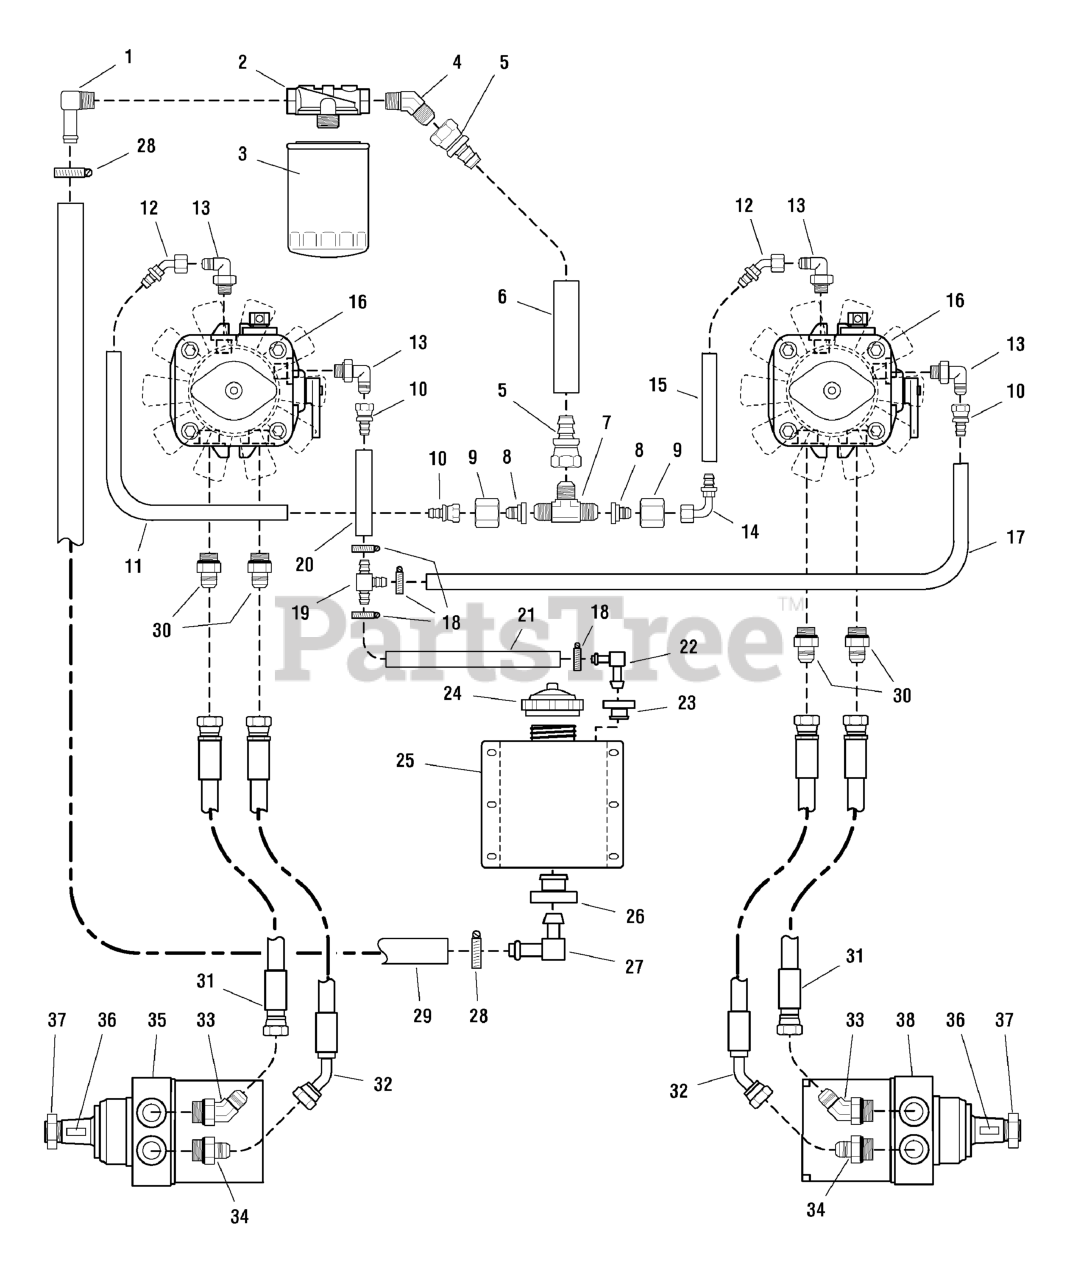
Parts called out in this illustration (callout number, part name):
1	FITTING, 1/2" NPT, 90 Deg.
2	FILTER HEAD
3	FILTER, HYDRAULIC, SERVICE PART (PKG)
4	FITTING, 1/2" NPT, 45 Deg.
5	FITTING, Straight Swivel
6	HOSE, Hydraulic, 7-1/2"
7	FITTING, Tee
8	ADAPTER, Tee
9	NUT, Adapter
10	FITTING, Straight Swivel
11	HOSE, Hydraulic, 13-3/4"
12	FITTING, 45 Deg. Swivel
13	FITTING, O-Ring, 90 Deg.
14	FITTING, 90 Deg. Swivel
15	HOSE, Hydraulic, 6-3/4"
16	HYDRAULIC PUMP, 10CC, w/ FAN
16	HUB & FAN KIT
17	HOSE, Hydraulic, 16-1/2"
18	CLAMP, #6 Hose
19	FITTING, TEE, 3/8" Hose
20	HOSE, Hydraulic, 6"
21	HOSE, Hydraulic, 17-1/2"
22	FITTING, Elbow, 3/8"
23	GROMMET
24	CAP, Hydraulic Oil Only
25	HYDRAULIC OIL RESERVOIR, Complete
26	GROMMET
27	FITTING, Elbow, 5/8"
28	CLAMP, #10 Hose
29	HOSE, Hydraulic, 18"
30	FITTING, O-Ring Adapter
31	HOSE ASSEMBLY, (21), HP, ST X ST
32	HYDRAULIC HOSE ASSEMBLY, 25"
33	FITTING, O-Ring, 45 Deg.
34	FITTING, O-Ring Adapter
35	HYDRAULIC WHEEL MOTOR-LEFT, Complete
36	KEY
37	NUT & COTTER PIN
38	HYDRAULIC WHEEL MOTOR-RIGHT, Complete
